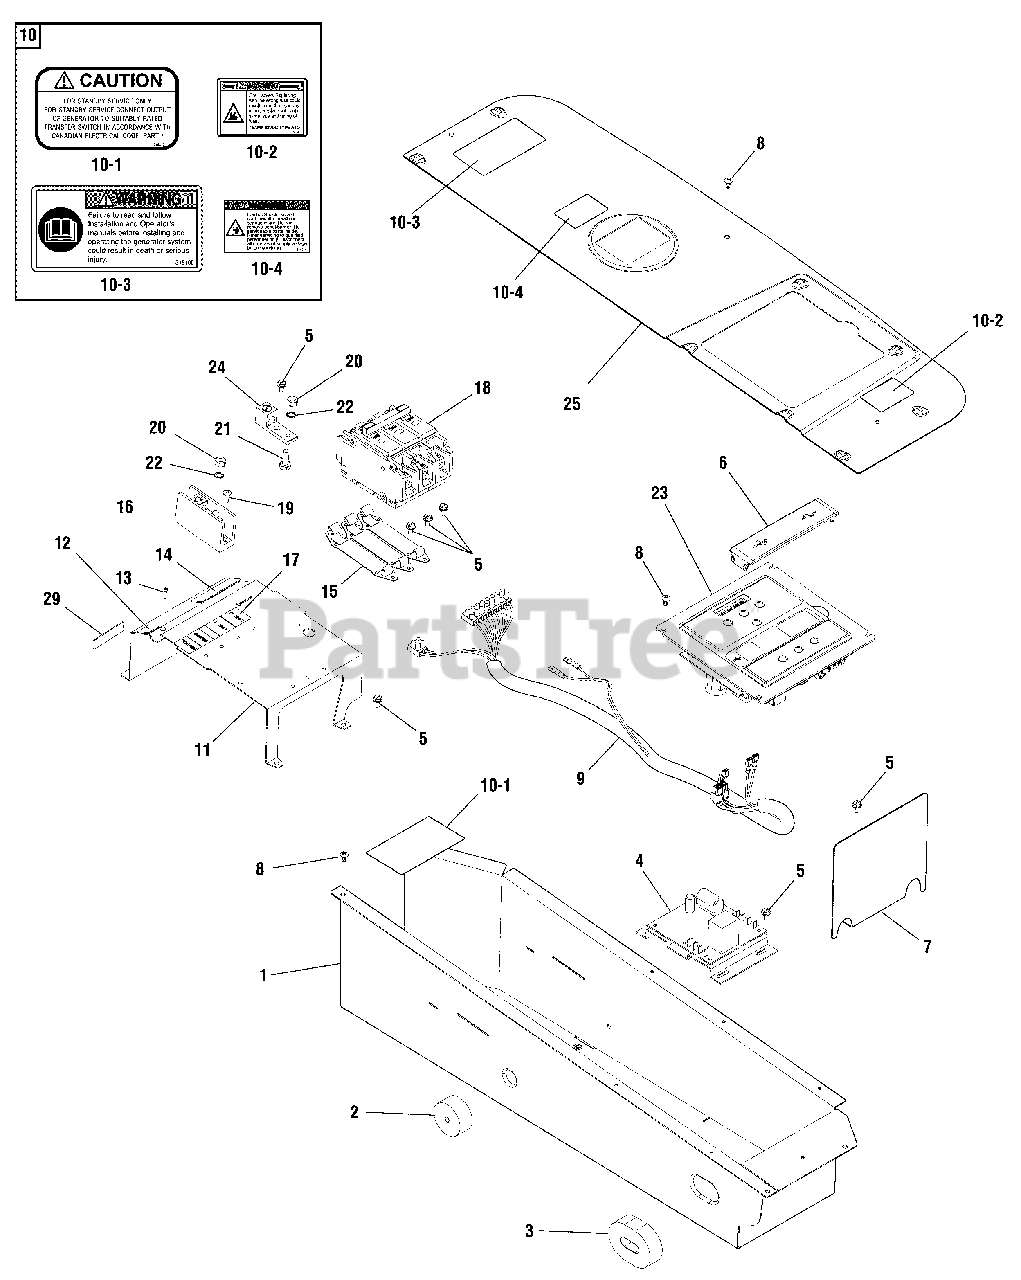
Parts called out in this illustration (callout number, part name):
2	SEAL
4	REGULATOR-VOLTAGE
10	DECAL SHEET-WARNINGS
10-1	DECAL-CAUTION, STANDBY
10-2	DECAL-FUSE WARNING
10-3	DECAL-WARNING, ELECTRIC SHOCK
10-4	DECAL-WARNING, READ MANUAL
13	* SCREW, M2.5-0.45 x 8
18	BREAKER-CIRCUIT
19	* SCREW, #10-32 x 3/4
20	* NUT, 1/4-20
21	* CAPSCREW, Hex Head, 1/4-20 x 3/4
22	* WASHER, Lock, Ext, M6
25	COVER-CONTROL PANEL BOX
